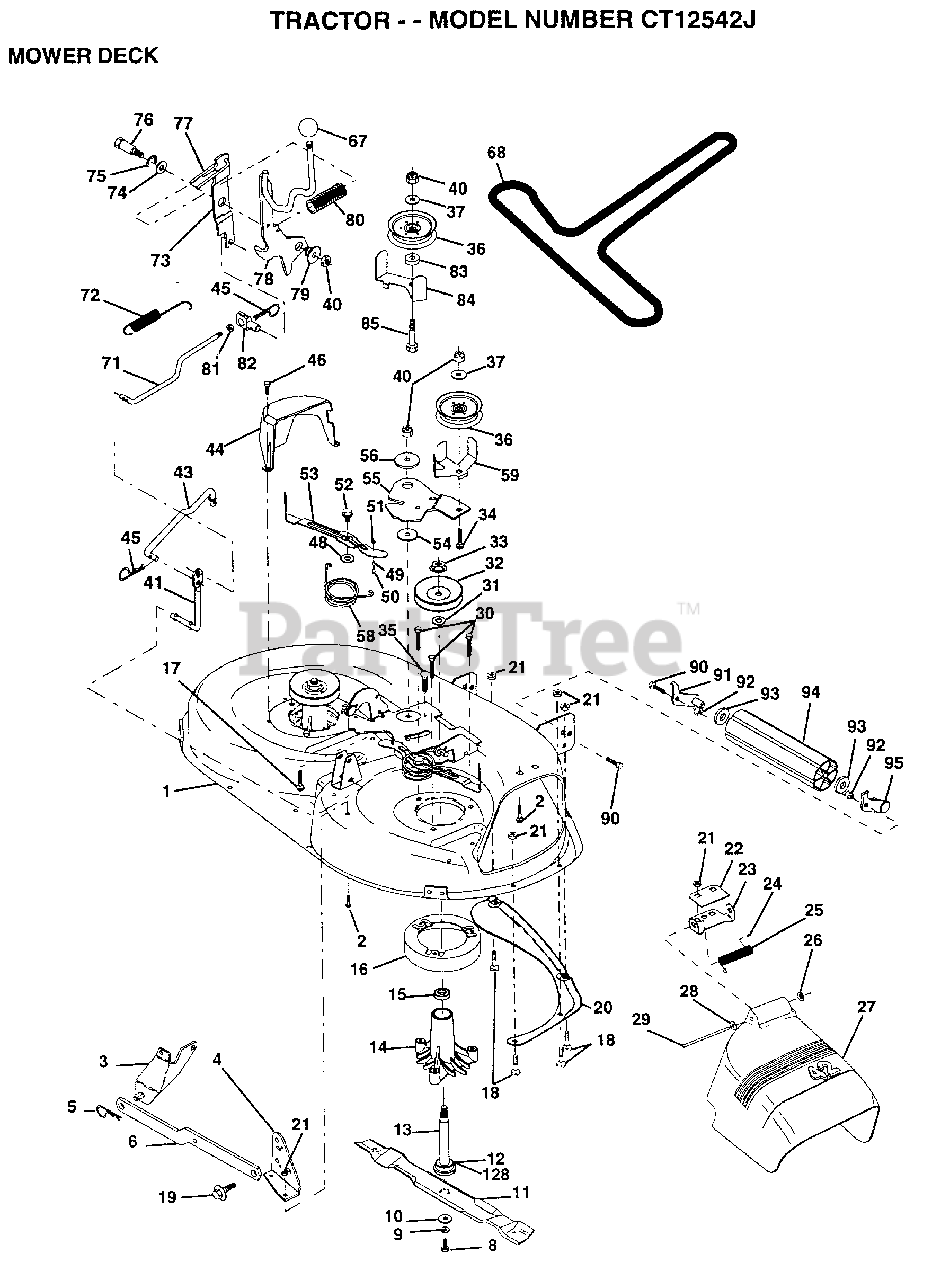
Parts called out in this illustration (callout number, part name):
1	DECK.WELD.42.
2	BOLT
3	BRKT ASM SWAY BAR
4	BRKT DECK SW BAR
8	BLADE BOLT
10	WASHER.HARD.BLADE
11	"BLADE.42"" HIPERF"
12	BEARING.BALL
14	HSG ASM MANDREL
15	BEARING
16	STRIPPER RND MWR
17	BOLT RDHD 3/8-16
18	BOLT
19	BOLT SHD 5/16-18
22	STIFFENER BRKT
23	DEFLECTOR BRKT
24	CAP-SLEEVE LT
25	SPRING TORSION
26	NUT PUSH M
27	DEFLECTOR.SHIELD
28	WASHER
29	HINGE ROD
31	WASHER
32	PULLEY.MANDREL.42
34	BOLT
35	XMAS TREE FASTNER
36	FLAT IDLER PULLEY
37	WASHER
41	PIVOT ROD
43	ROD CLUTCH W/NIBS
44	GUARD MAND LH BLK
45	RETAINER M
46	SCREW.1/4-20X5/8
48	HARD SMALL WASHER
50	SHOULDER BOLT
51	LOCKNUT
52	BOLT.SHLD.5/16-18
53	BRAKE PAD ARM ASM
54	HARDENED WASHER
56	SPACER RETAINER
58	SPRING TORSN BRAK
59	GUARD IDLER TUV
67	CONTROL KNOB LT
68	BELT.V.T-PATH
71	ROD CLUTCH 38/42
72	RETURN SPRING
73	CLUTCH ARM SECOND
74	WASHER
75	RING
76	SHOULDER BOLT
77	SPRING KEEPER
78	LEVER ASM CLT PRM
79	BUSHING
80	SPRING.CLUTCH.MWR
81	NUT
82	TRUNION ADJ
83	WASHER
85	BOLT RDHD 3/8-16
90	BOLT
92	NUT
93	WASHER
128	WASHER.FELT.
